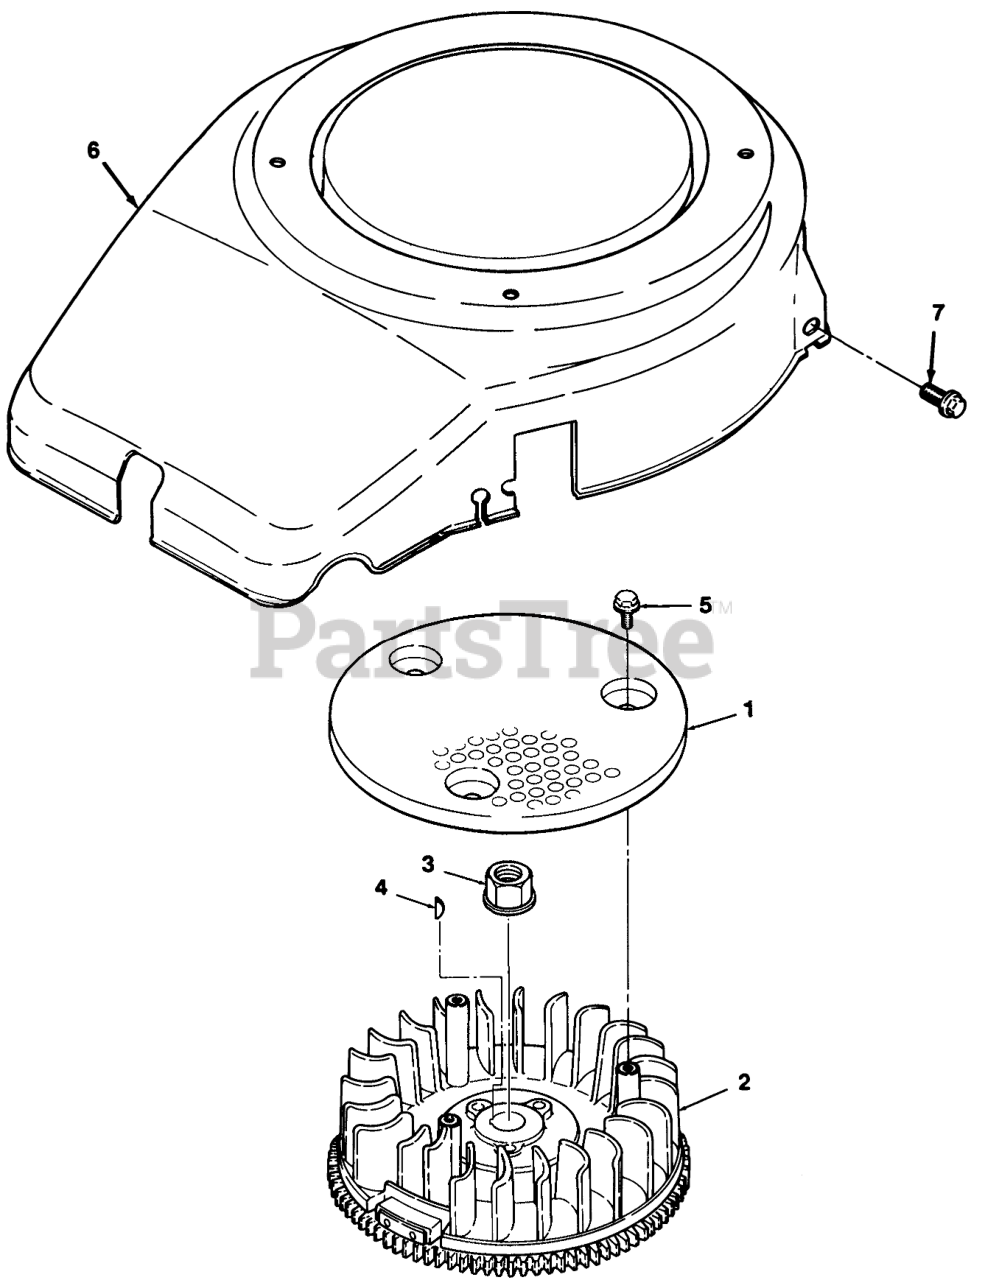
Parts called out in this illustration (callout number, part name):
1	Screen
2	WHL-ASS'Y BLOWER
4	Screw-Hex Hd.
5	NUT-FLANGE M18
6	Blower Housing
7	BOLT-HHF M6 X 12MM
